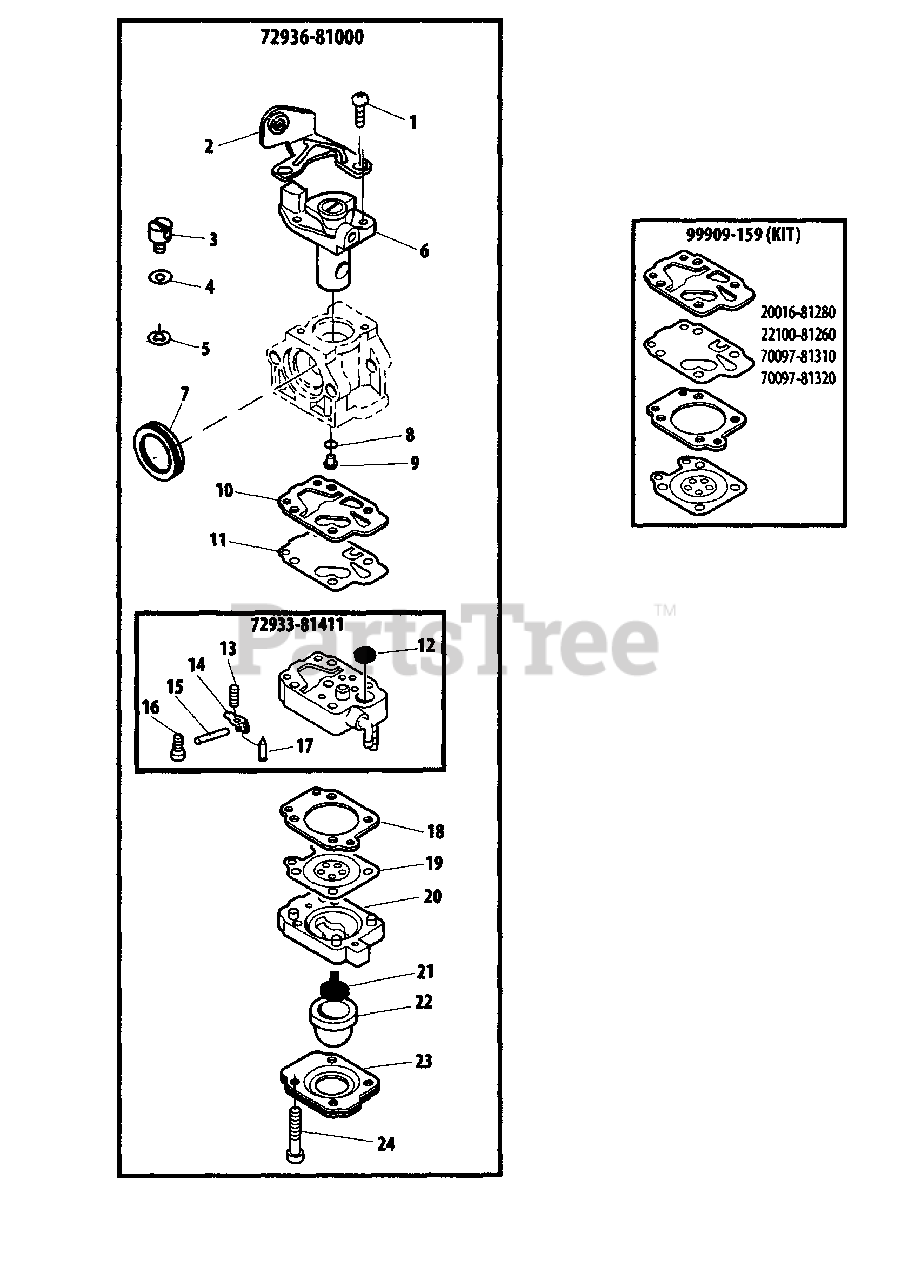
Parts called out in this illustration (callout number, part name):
1	SCREW
2	BRACKET, THROTTLE CABLE
3	SWIVEL
4	WASHER
5	E-RING
6	THROTTLE VALVE ASSY
7	RING, PACKING
8	O-RING
9	JET
10	GASKET, PUMP
11	DIAPHRAGM, PUMP
12	SCREEN, FUEL INLET
13	SPRING, METERING LEVER
14	LEVER, METERING
15	PIN, METERING LEVER
16	SCREW
17	VALVE, INLET NEEDLE
18	GASKET, METERING DIAPHRAGM
19	DIAPHRAGM, METERING
20	BODY ASSY, PURGE
21	VALVE, CHECK
22	BULB, PURGE
23	RETAINER, PURGE BULB
24	SCREW
72933-81411	BODY ASSY, PUMP
72936-81000	CARBURETOR
99909-159	GASKET / DIAPHRAGM KIT
